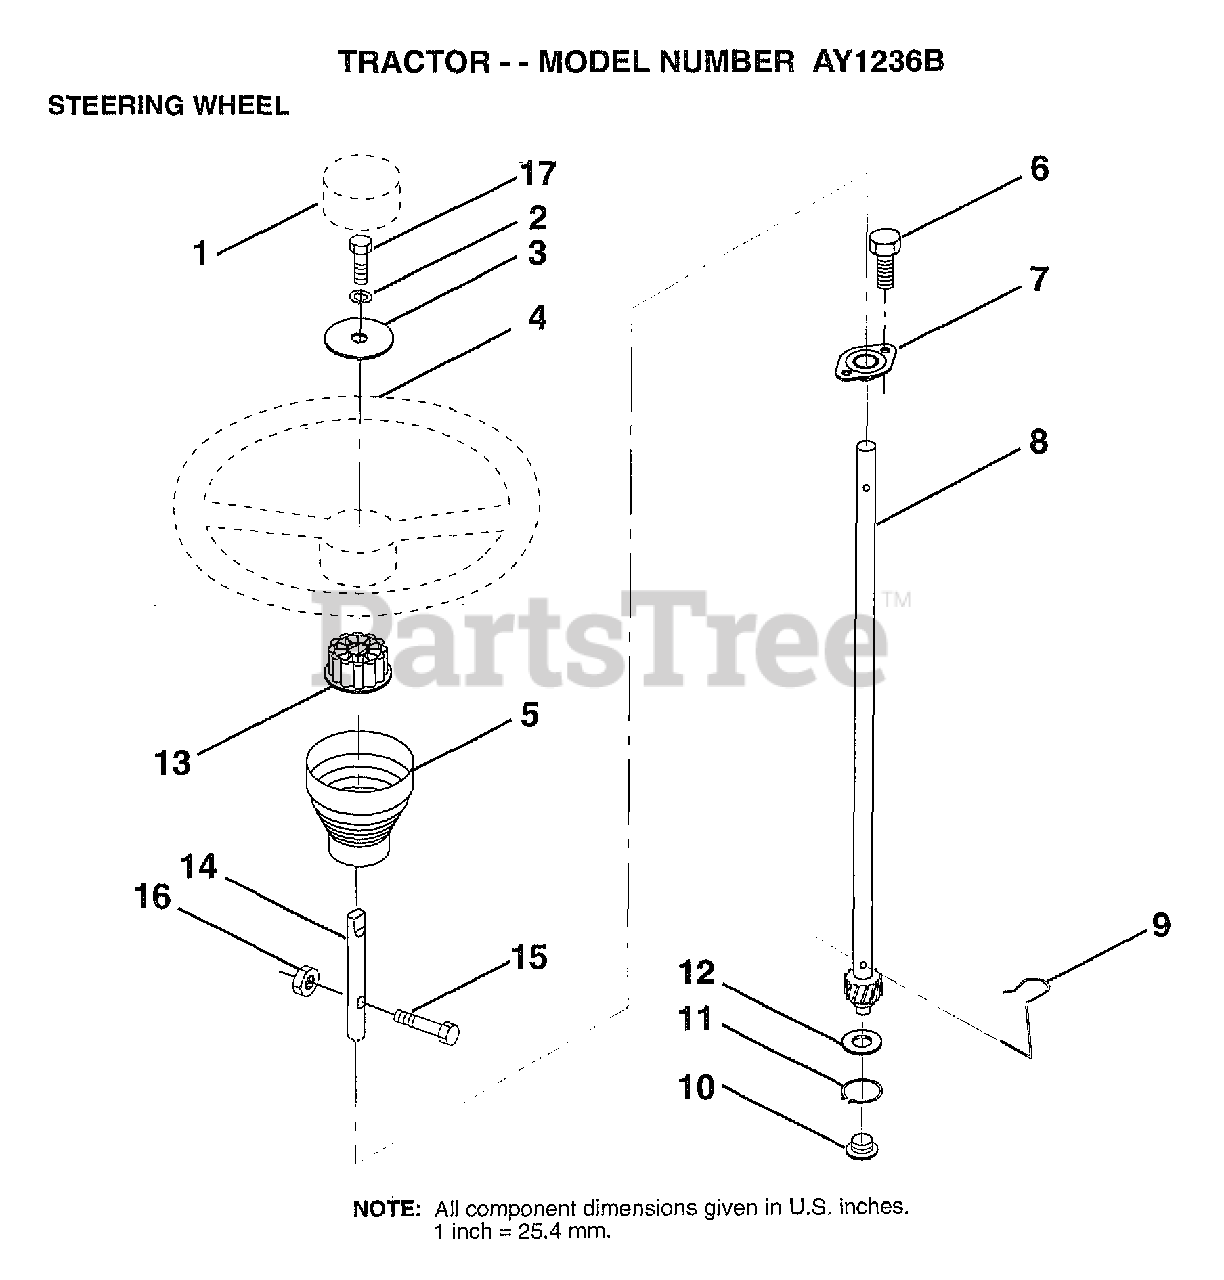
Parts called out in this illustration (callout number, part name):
1	ST WHL INSERT CAP
2	LOCKWASHER
3	WASHER T
5	SLEEVE STEERING
8	SHAFT.STEERING.LR
9	STEERING CLIP
10	BUSHING STEER LWR
11	RING
12	WASHER LT
13	ADAPTER LT
14	EXT SHAFT STEERIN
15	BOLT
16	NUT
